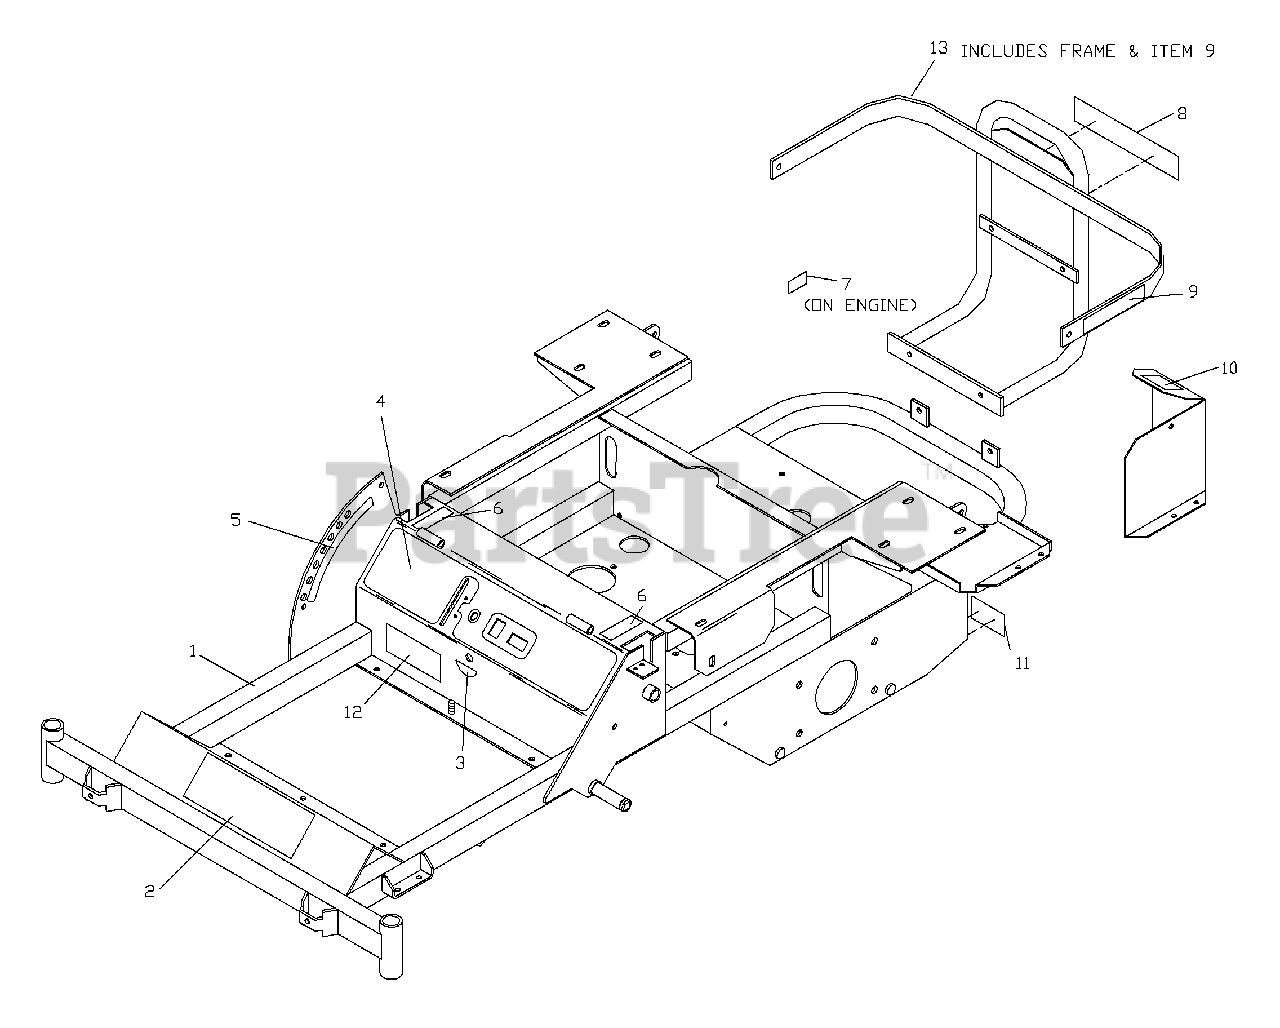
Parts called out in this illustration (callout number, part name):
1	FRAME W/DECALS (KAWASAKI
1	FRAME W/DECALS (KOHLER)
2	DECAL, HUSQVARNA
3	DECAL, FUEL VALVE
4	DECAL, CONSOLE (KAWASAKI)
4	DECAL, CONSOLE (KOHLER)
5	DECAL, LOCATOR
6	DECAL, MOTION CONTROL
7	DECAL, EXHAUST
8	DECAL. HUSQVARNA
9	DECAL, BATTERY
10	DECAL, PROP. 65
11	DECAL, DANGER
12	DECAL, NASCAR
13	ENGINE GUARD W/DECALS
